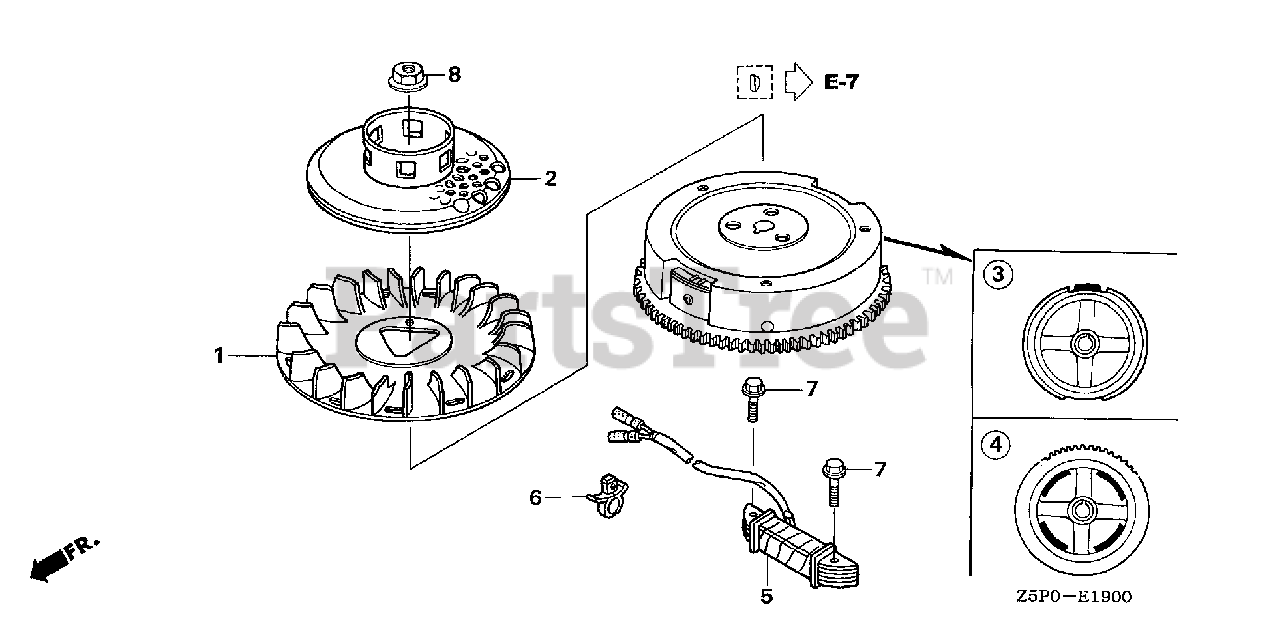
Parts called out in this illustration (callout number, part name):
1	FAN, COOLING
2	PULLEY, STARTER (SCREEN GRID)
8	NUT, SPECIAL (16MM)
